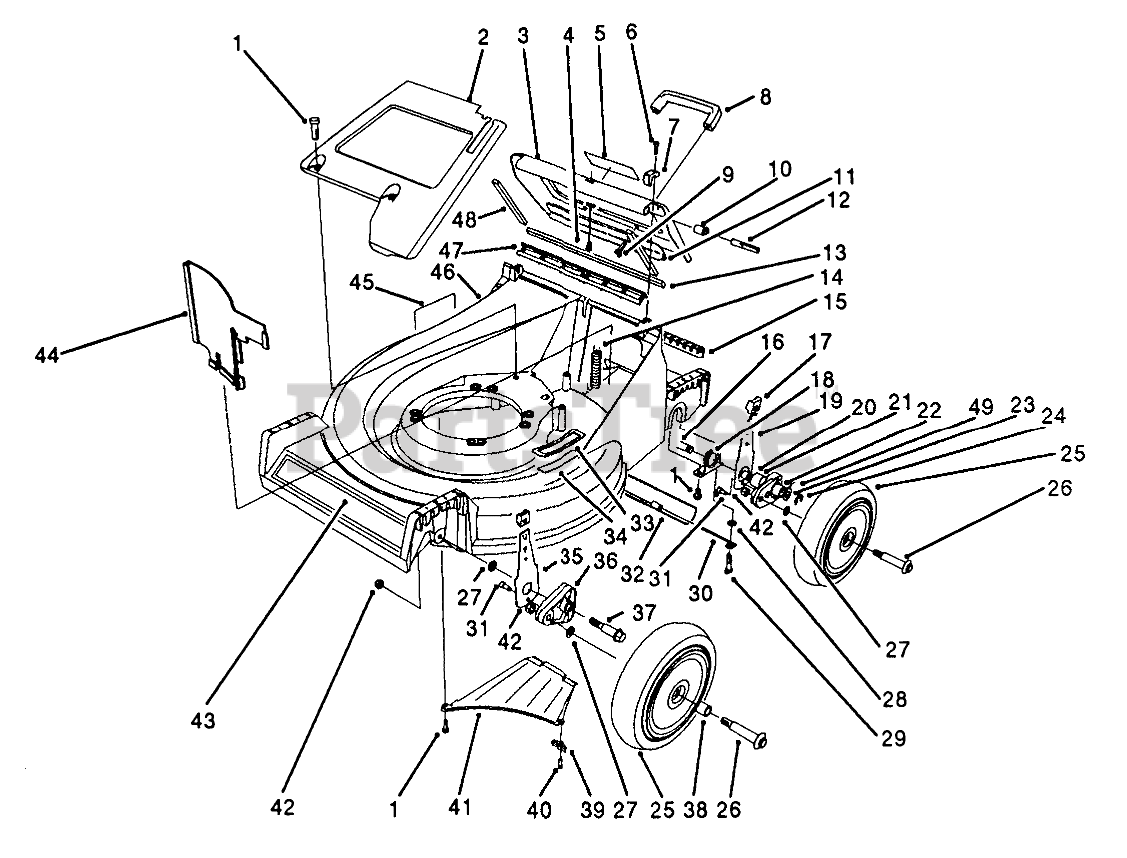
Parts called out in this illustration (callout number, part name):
1	SCREW-HWHTF
2	PaneI-Screen
3	Door-Discharge (Incl. Ref. #5, 11, 13, & 48)
4	DOOR CABLE
5	DECAL - WARNING
6	SCREW-HSH
7	HINGE CLAMP
8	HANDLE-DOOR
9	SCREW-HWH
10	DOOR BUSHING
11	DOOR - BRACE
12	HINGE PIN
13	DOOR END SEAL
14	EXTENSION-SPRING
15	ACCESS COVER
16	SHAFT - AXLE
17	KNOB-ARM
18	CAP-END
19	SPRING ARM ASM
20	BUSHING
21	Pivot Arm Ass-y (Incl. Ref. #20, 22 & 49)
22	BUSHING
23	WASHER-ARM, PIVOT
24	RING-RETAINING
25	Wheel & Tire Ass-y (Incl. Ref. #38)
26	WHEEL BOLT
27	WASHER
28	WASHER-PLAIN
29	SCREW-SHOULDER
30	SHIELD HANGER
31	SCREW-HSH, THREAD FORMING
32	SHIELD - TRAILING
33	STEP PAD
34	STEP PAD DECAL
35	FRONT SPRING ARM ASM
36	ARM-PIVOT, FRONT
37	BOLT-SHOULDER
38	BUSHING
39	Bracket-Discharge
40	SCREW-HWHTF
41	Ramp Discharge
42	NUT-LOCK
43	DECAL - DECK
44	PANEL-VERTICAL
45	DECAL-DANGER
46	Housing Assembly (Incl. Ref. #29, 33, 34, & 45)
47	DOOR SEAL
48	DOOR SIDE SEAL
49	FITTING-GREASE
